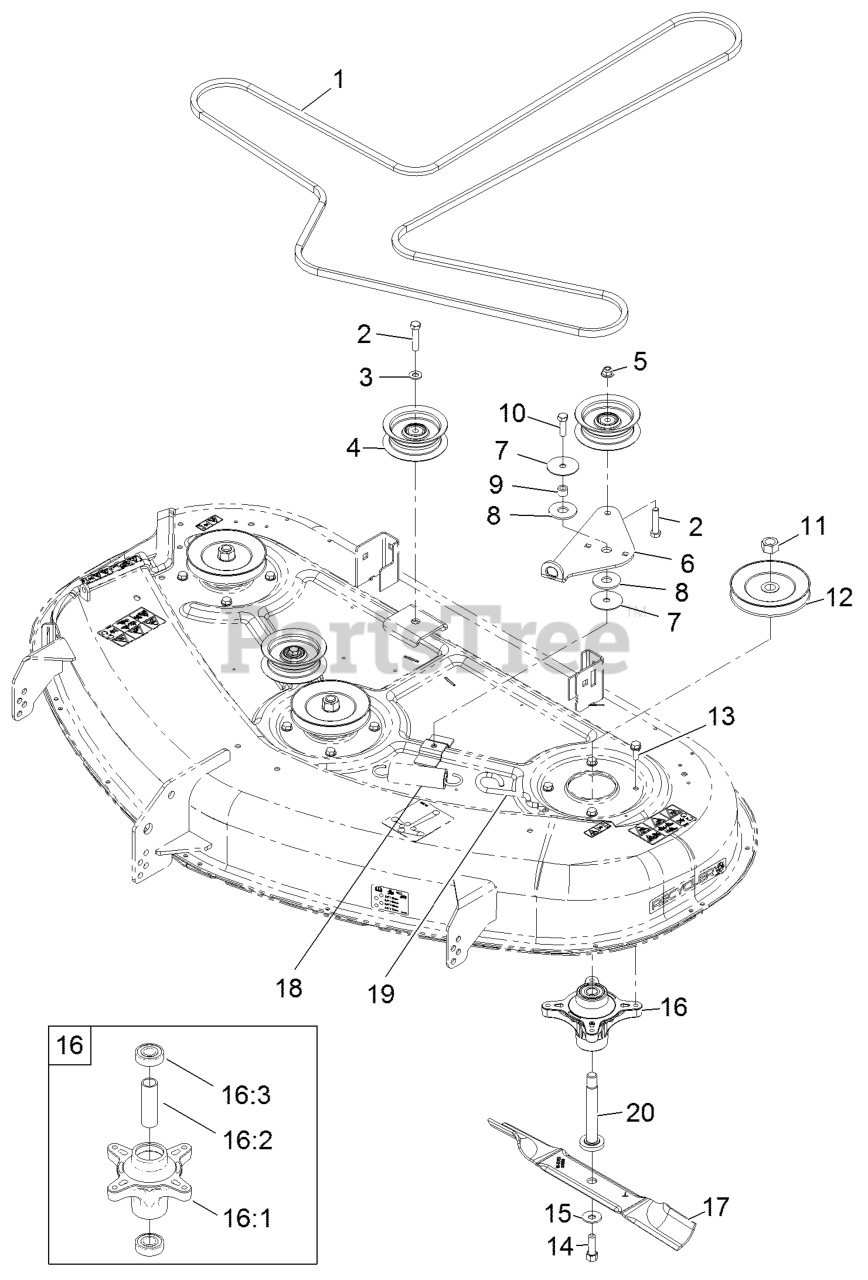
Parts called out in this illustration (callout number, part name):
1	V-BELT
2	SCREW-HH
3	WASHER-FLAT
5	NUT-HF, NI
6	ARM-IDLER
8	WASHER-FRICTION, COMPOSIT
10	SCREW-HH
11	NUT-HEX
13	SCREW-TAPTITE
14	SCREW-HH
15	WASHER-BELLEVILLE
16	SPINDLE ASM
17	BLADE-HI LIFT
18	SPRING-EXTENSION
19	HOOK-RETURN, SPRING
20	SHAFT-SPINDLE
